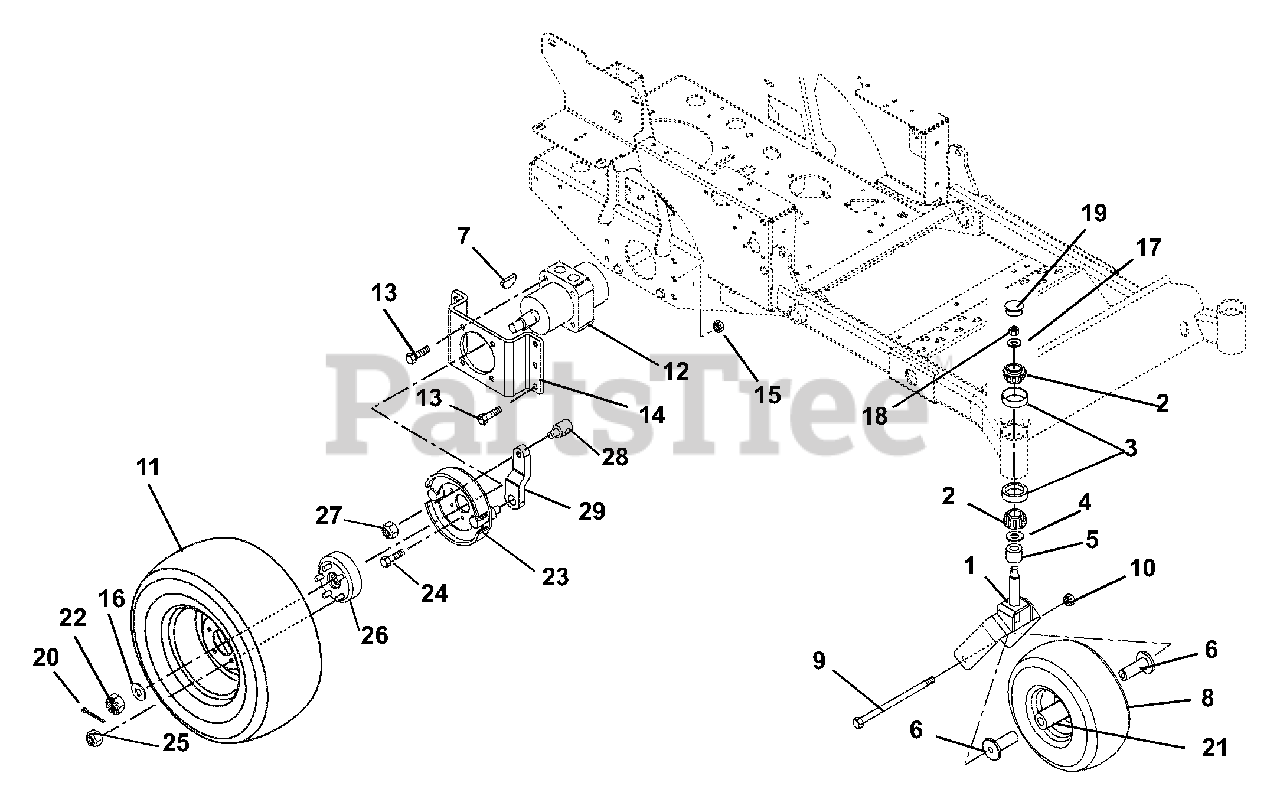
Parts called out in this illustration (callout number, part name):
1	Weldment, Front Fork
2	Bearing, Cone with Grease, 1.0 x .58
3	Bearing, Cup 1.980 x .420
4	Bearing Seal 1.5 x 2 x .18
5	Spacer, PM, 1.03 I.D. x 1.5 O.D. x .375
6	Spacer, Wheel
7	Key, Woodruff .31 x 1.00
8	Wheel/Tire Assembly 5.25 x 13.00
9	Bolt, Hex .50-13 x 7.50 Grade 5
10	Nut, Nyloc Flange .50-13
11	Wheel, Tire Assembly 20 x 10-10
11	Tire, 20 x 10.00 Multi Trac C-S
12	Motor, Hydraulic Wheel
13	Bolt, Hex .38-16 x 1.00 Grade 5
14	Bracket, Wheel Motor
15	Nut, Nyloc Flange 3/8-16
16	Washer, Flat Steel .755 x 1.375 x .062
17	Washer, Flat Steel .812 x 1.50 x .135
18	Nut, Center Lock Jam Nut .75-16
19	Cap, Dust
20	Pin-Cotter .09 x 1.25 Extended Prong Square Cut
21	Bearing, 25MM I.D. x 52MM OD x 15MM
22	Nut, Hex .75-20
23	Brake, Mechanism with Pad
24	Screw, Socket Head M6 x 16 Grade 5
25	Nut, Lug .50-20
26	Hub, 5-Bolt Brake Drum
27	Nut, Center Lock Jam .31-18
28	Pin, Pivot
29	Arm, Brake Hydro-Gear
